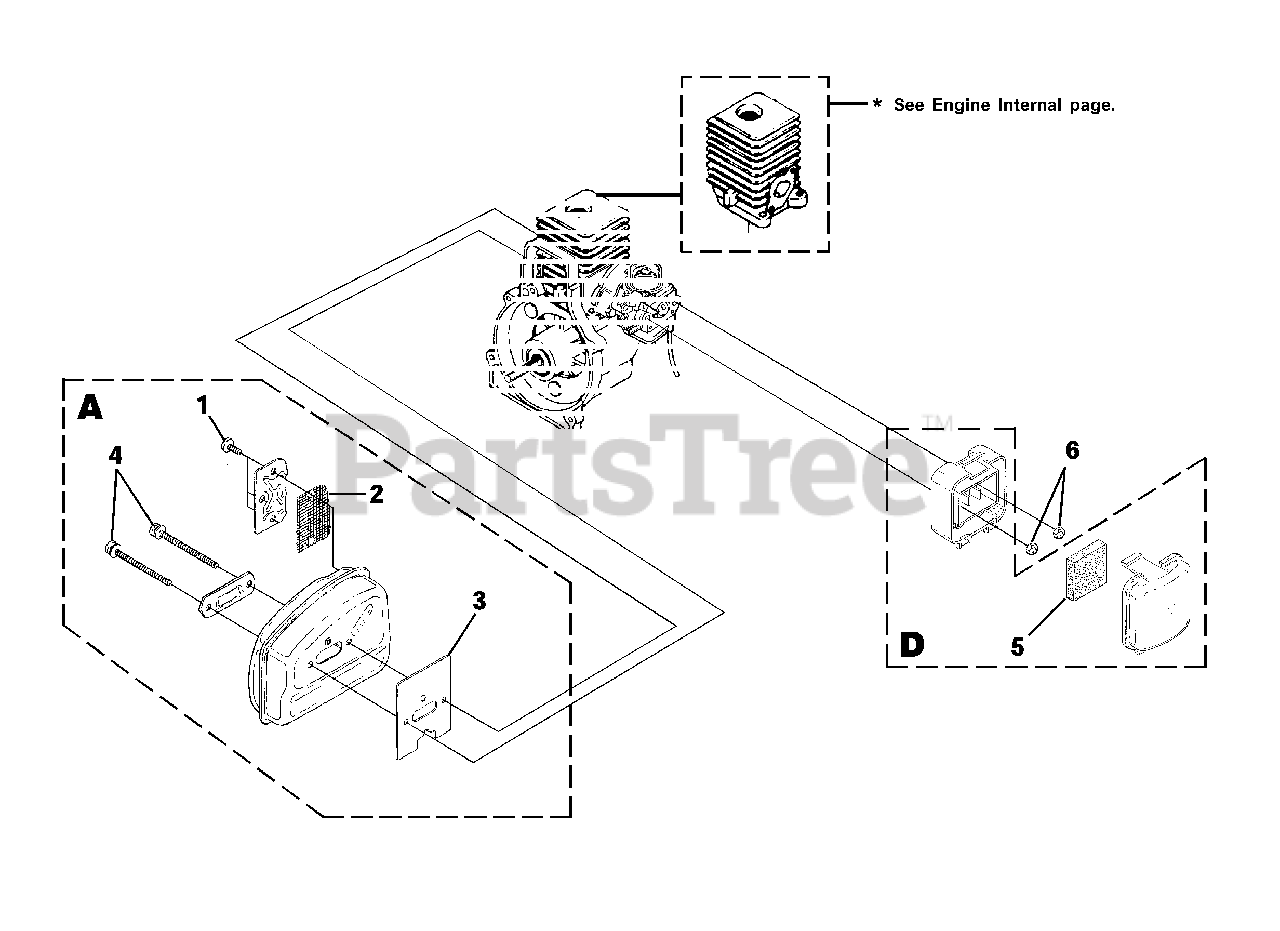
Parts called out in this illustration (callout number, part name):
1	SCREW, Taptite- (8-32 X 3/8")
2	SCREEN-Spark
3	GASKET-Muffler
4	SCREW, Truss Hd. - (10-24 X 2.188)
5	FILTER-AIR
6	NUT-Hex (10-24)
A	MUFFLER ASSY.
D	AIR FILTER KIT (Clutch)
